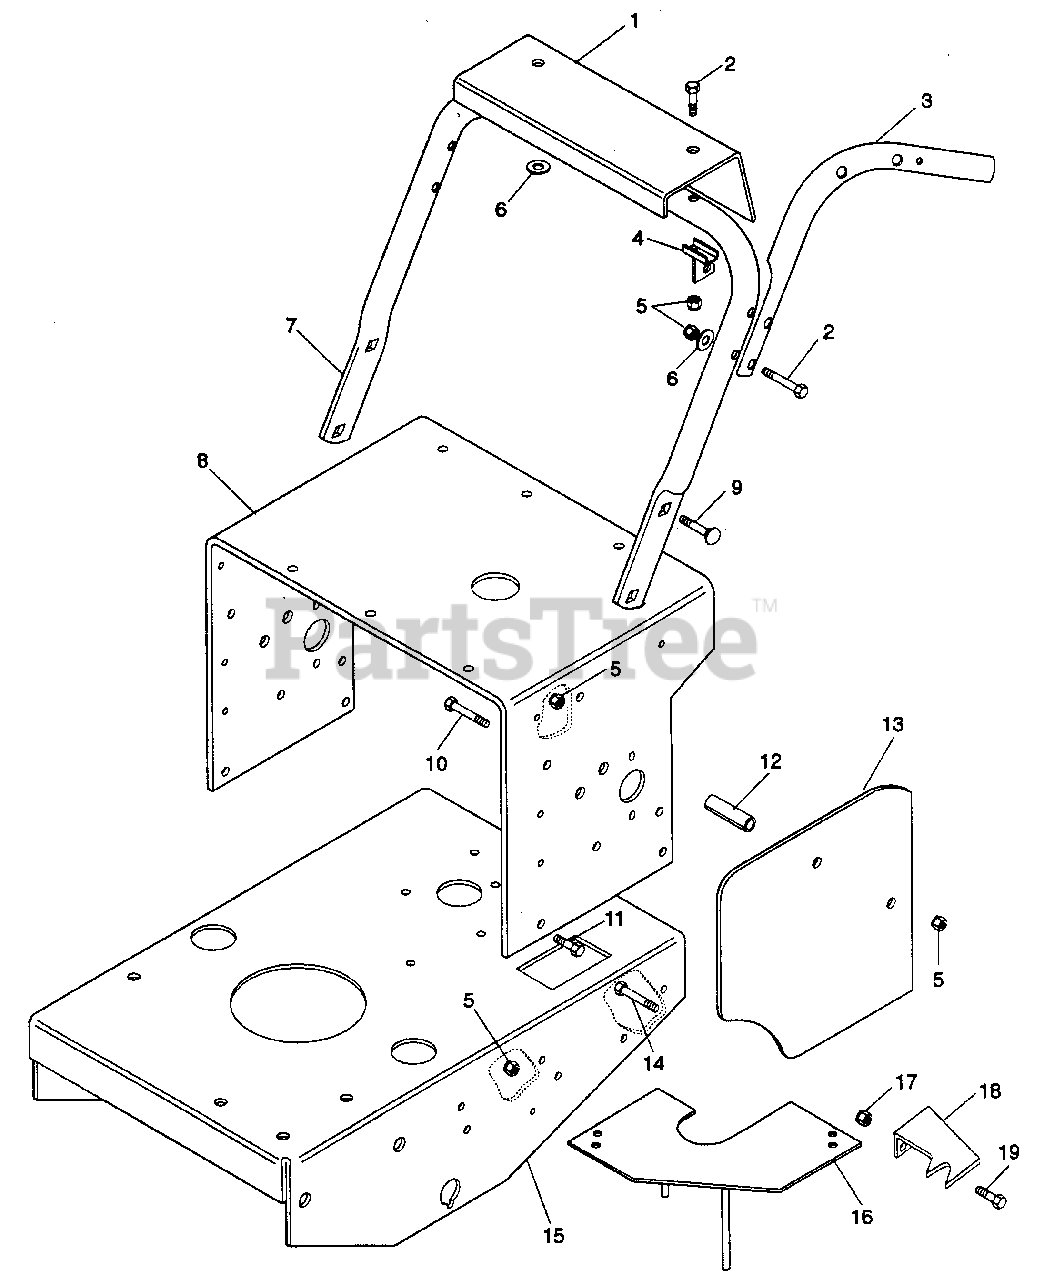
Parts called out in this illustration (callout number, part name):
1	PNL, SILK SCREENED
2	BLT-HEX .38-16 X 2.00
3	HANDLEBAR L.H.
3	HANDLEBAR R.H.
4	PTO LEVER MTG BKT
5	NUT-LK-NYL .375-16 PL
6	WSHR-FL-STL .406 X .812 X .065 PL
7	LOWER HANDLEBAR, PRO 150
8	PRO-150 TOP FRAME
9	BLT-RDHDSQNK .38-16 X 1.0 PL
10	BLT-HEX .38-16 X 4.00
11	BLT-HEX .38-16 X 1.00 PL GR 5
12	BSHG, SPACER, 3.25 X 3/8 ID X 5/8 OD
13	GUARD, DRIVE PRO-150 SIDE CVR
14	BLT-HEX .38-16 X 1.38
15	PRO-150 MAIN FRAME
16	WLDT, BELT FINGER, PRO-150
17	NUT-LK-NYL .312-18 PL
18	CLEANER, PLLY GROOVE L.H.
18	CLEANER, PLLY GROOVE R.H.
19	BLT-HEX .31-18 X .625 GR-5
